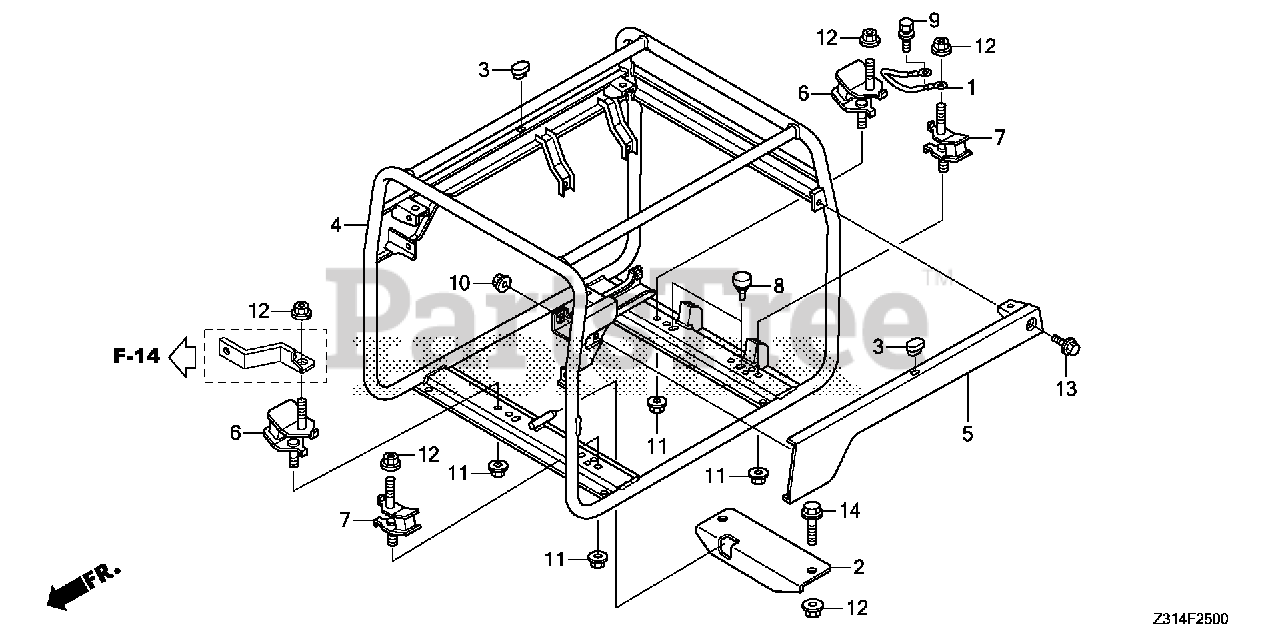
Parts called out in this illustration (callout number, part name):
1	CABLE, SUB-GROUND
2	BRACKET, STOPPER
3	RUBBER, FUEL TANK MOUNTING
4	FRAME *NH105* (CL)(COO) (MAT BLACK)
5	FRAME, R. SIDE *NH105* (COO)(FOR U.S.A.) (MAT BLACK)
6	RUBBER (LOWER)
7	RUBBER (LOWER)
8	RUBBER, BUMP STOP
9	BOLT, GROUND (6X16) (WASHER 12.5MM) (ZN)
10	NUT, FLANGE (6MM)
11	NUT, FLANGE (8MM)
12	NUT, FLANGE (10MM)
13	BOLT, FLANGE (6X12)
14	BOLT, FLANGE (10X40)
